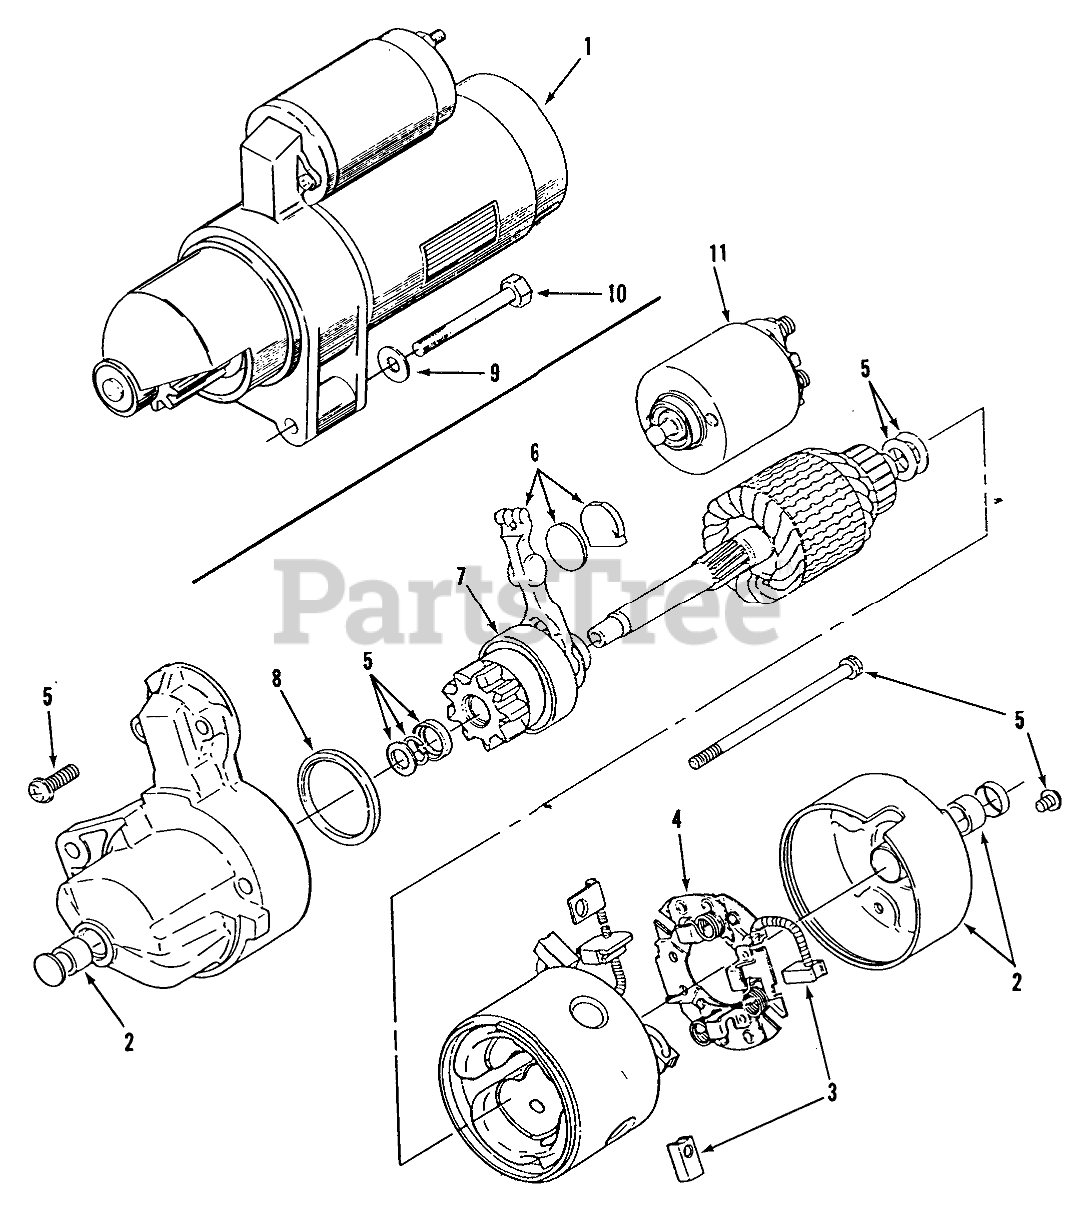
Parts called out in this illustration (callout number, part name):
1	Starter, Complete-See Components Below
2	Bushing Kit (Includes Frt Bushing and Rear Cap w/Bushing)
3	Starter Brush Kit (Includes Positive Brush (2) and Negative Brush w/Pigtail)
4	Starter Brush Holder (Includes Brush Holder w/Negative Brush)
5	Starter Hdwr Kit (Includes Solenoid Screws (2), Brush Holder Screws (2), Thru Bolts (2), Armature Shims (2), Pinion Stop Collar, and Pinion Retaining Ring)
6	Starter Shift Lever Kit (Includes Shift Lever, Wear Plate and Rubber Plug)
7	Starter Clutch (Includes Pinion Gear w/Clutch)
8	Dust Seal
9	Washer, Flat
10	Cap Screw 5/16-18 x 3-1/2
11	Starter Solenoid Kit (Includes Solenoid, Spring and Plunger)
